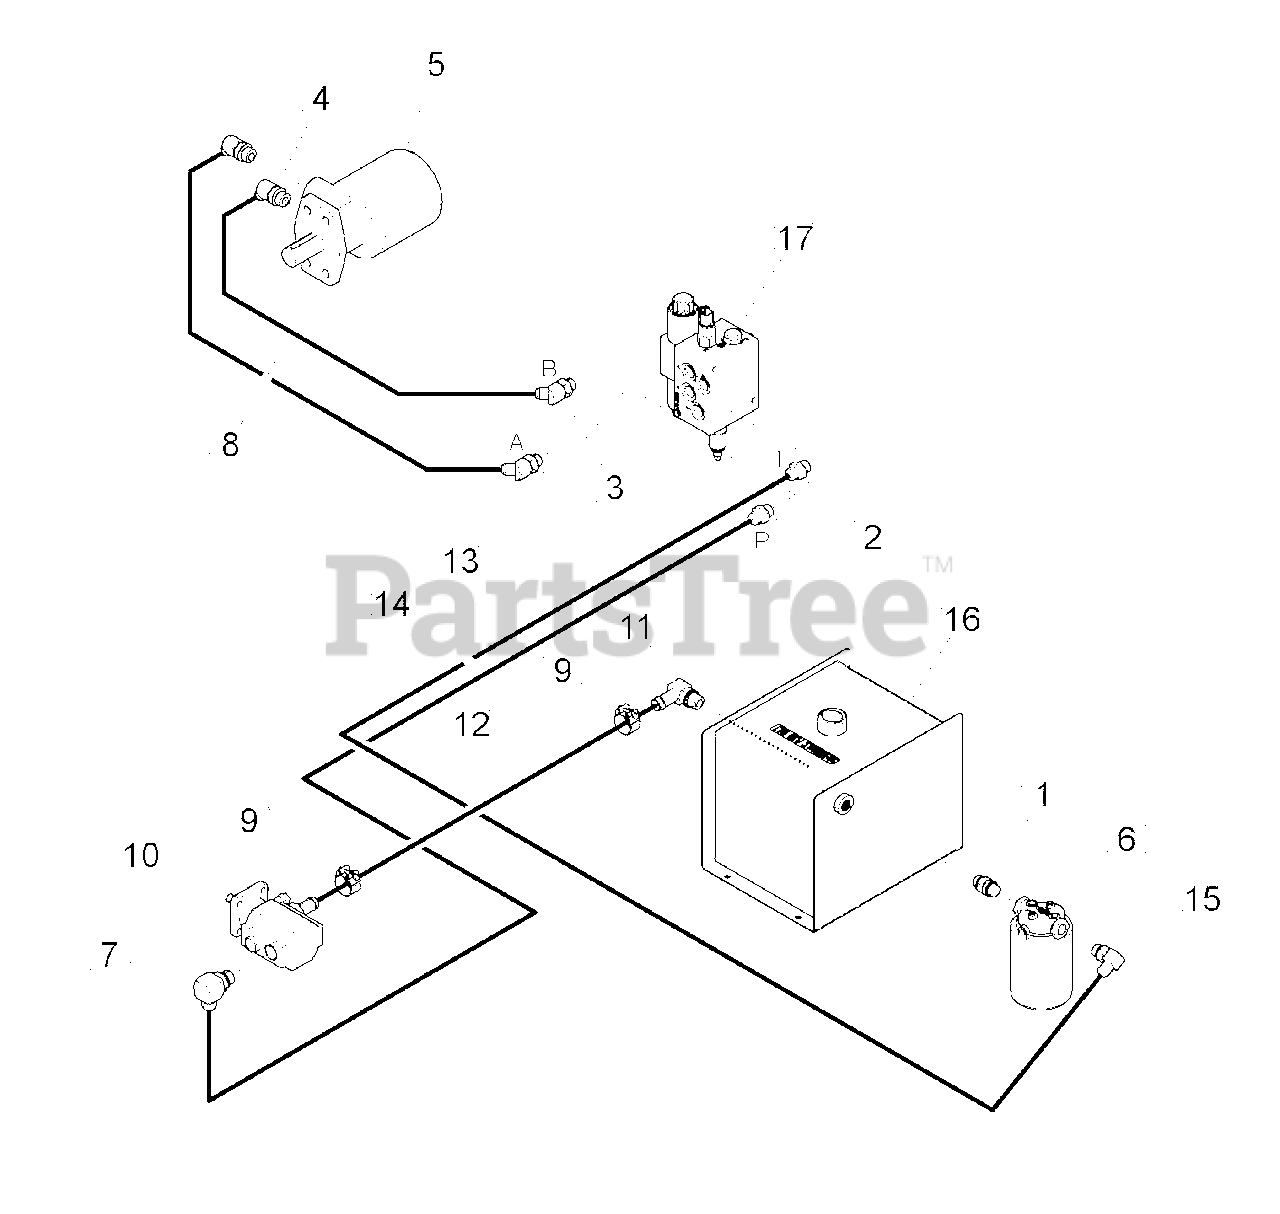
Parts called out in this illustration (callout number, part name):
1	ADAPTER, -8 MORING / -8 MORING ADJ
2	ADAPTER, -8 MORING / -8 MJIC
3	ADAPTER, -8 MORB / -8 MJIC 45 DEG.
4	ADAPTER, -10 MORING / -8 MJIC 45 DEG.
5	MOTOR, 45 CU IN HYDRAULIC
6	ASSEMBLY, HYDRAUILC FILTER
7	ADAPTER, -10 MORING / -10 MJIC 90 DEG.
8	HOSE, .375 X 36" -8 FMJIC / -8 FMJIC
9	CLAMP, 1-5/32 TO 7/32 OD RANGE T-BOLT
10	PUMP, 2 STAGE CW HI/LO 0.605 DISP.
11	ADAPTER, -10 MORING / .75 90 DEG. HOSE
12	HOSE, .75 ID X 38" 100R4 HYD
13	HOSE, .50 X 84" -8 FMJIC / -8 FMJIC
14	HOSE, .50 X 66" -8 FMJIC / -10 FMJIC 90 DEG.
15	ADAPTER, -8 MORING / -8 MJIC 90 DEG.
16	ASSEMBLY, HYDRAULIC TANK
17	ASSEMBLY, HYDRAULIC FEED FLOW VALVE
